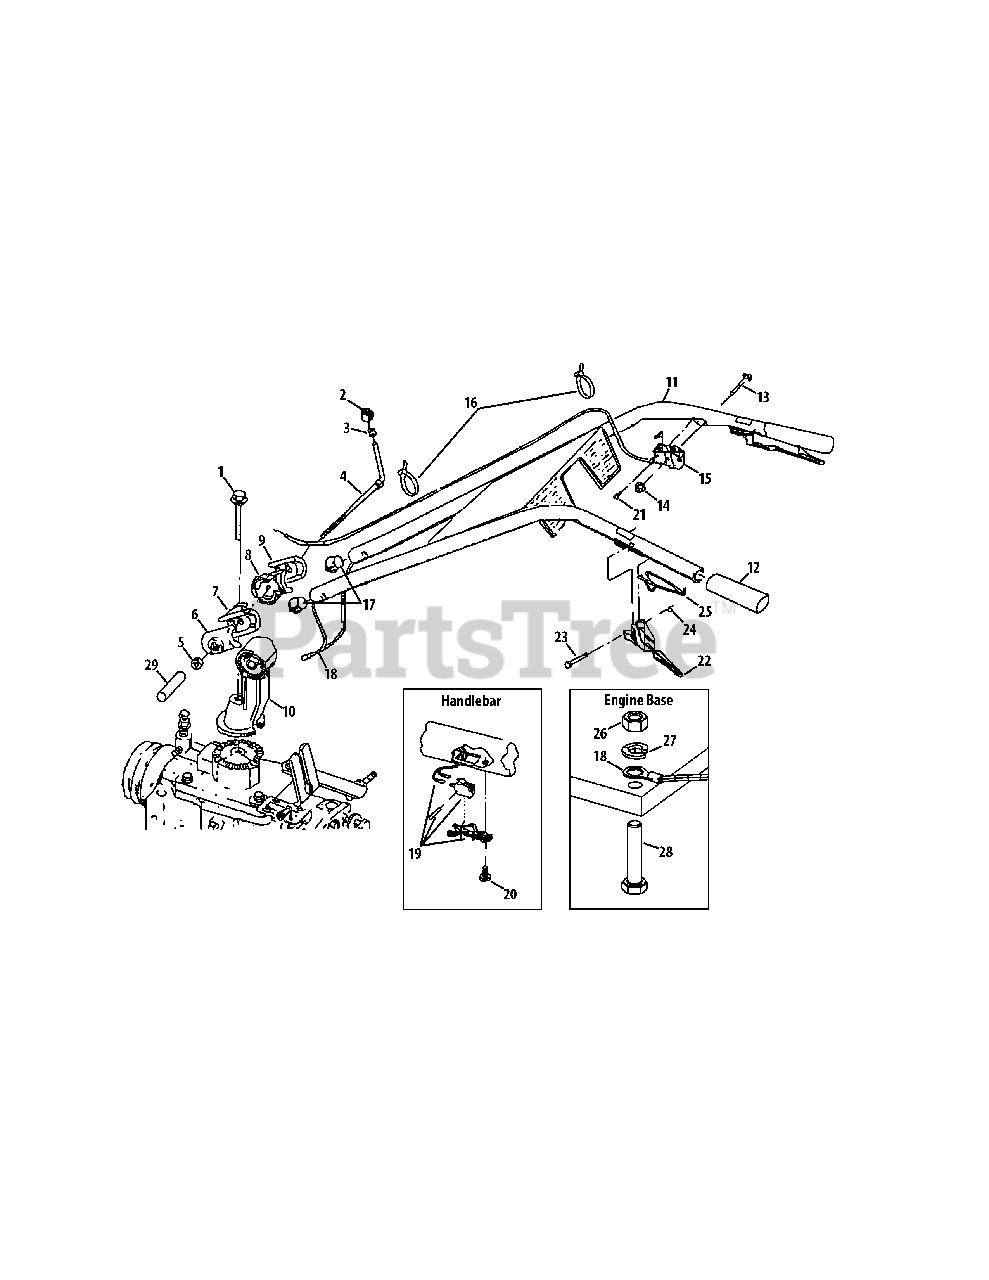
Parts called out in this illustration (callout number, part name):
1	Hex Bolt, 1/2"-13 x 3-1/2"
2	Handlebar Height Adjustment Knob
3	Retaining Ring
4	Handlebar Height Adjustment Stud
5	Hex Nut, 1/2"-13
6	Handlebar Hgt, Adj. Clamp (LT)
7	Handlebar Hgt. Adj. Ratchet (LT)
8	Handlebar Hgt. Adj. Ratchet (RT)
9	Handlebar Hgt. Adj. Clamp (RT)
10	Handlebar Mounting Base
12	Handlebars Grip
13	Curved Head Bolt, 1/4"-20 x 2"
14	Hex Nut, 1/4"-20
15	Throttle Control & Cable, 66"
16	Plastic Tie
17	Wire Harness Retainer Plug
18	Handlebar Wire Harness Assembly
19	Switch Assembly
20	Pan Head Screw, #10-16 x 1/2"
21	Phillips Head Screw, 10-32
22	Operator Presence Control Lever
23	Pivot Pin
24	Retaining Ring
25	Return Spring
26	Hex Nut, 5/16"-18
27	Washer, 5/16"
28	Hex Head Screw, 5/16"-18 x 1.5
